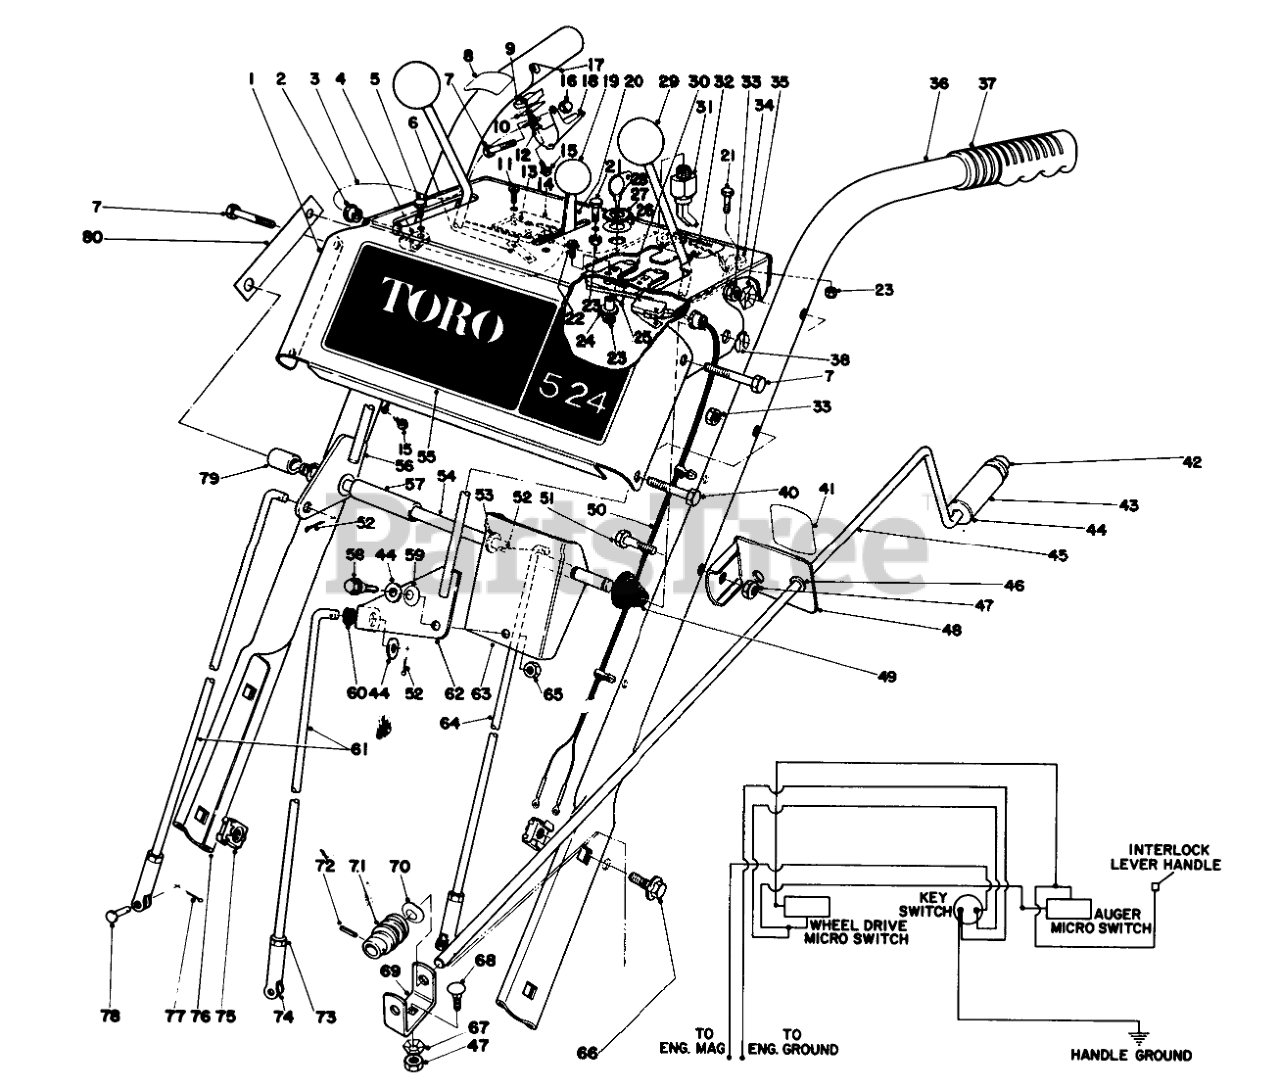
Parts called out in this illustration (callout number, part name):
1	Escutcheon
2	Snap Bushing
3	WIRE ASM
4	PLASTIC CLIP
5	SCREW
6	NUT-SPEED
7	SCREW-HH
8	INTERLOCK DECAL
9	Insulator
10	INTERLOCK CONTACT
11	SCREW-SPH
12	WASHER INSULATOR
13	MICRO SWITCH
14	SWITCH MTG PAD
15	SCREW
16	NUT-CAP
17	INTERLOCK SPRING
18	SAFETY INTRLOCK LEVER
19	CONTROL KNOB
20	Throttle Control
21	HEX HEAD SEMS 10-24X1/2
22	SCREW-SRH
23	Nut
24	INTERLOCK SPACER
25	INTERLOCK SPRING
26	WASHER-TOOTH, INTERNAL
27	NUT-HH
28	Key
30	Slide Interlock
31	SWITCH-ON / OFF
32	INSTR DECAL
33	NUT-LOCK, CONE
34	CABLE CLAMP
35	Washer
36	LEFT HANDLE
37	Grip Handle
38	RING-CLIP
40	SCREW-HH
41	CHUTE DECAL
42	RETAINER-PUSH ON
43	CHUTE CONTROL GRIP
44	WASHER-FLAT
45	CHUTE CONTROL ROD
46	Bushing
47	NUT-LOCK, NI
48	Chute Control Rod Mounting (Incl. Ref. #41 & 46)
49	CONICAL SPRING
50	Wire Harness
51	SCREW-HH
52	PIN-COTTER
53	WASHER-FLAT
54	PIVOT ROD
55	ESCUTCHEON DECAL
56	LEVER WA
57	SHIFT LEVER SPACER
58	SHOULDER SCREW
59	7/16 SPRING WASHER
60	GROMMET-RUBBER
61	SPEED SELECTOR ROD
62	SHIFT LEVER WA
63	SHIFT BRACKET
64	TRACTION CONTROL ROD
65	NUT-LOCK, CONE
66	SCREW-HHF
67	WASHER-LOCK
68	BOLT-CARR
69	WORM BRACKET
70	WASHER-SPRING
71	GEAR-WORM, CHUTE
72	PIN-SPRING
73	NUT-HJ
74	Clevis
75	Retained Nut
76	RIGHT HANDLE
77	PIN-COTTER
78	PIN-CLEVIS
79	AUGER LEVER SPACER
80	ESCUTCHEON SUPT STRAP
